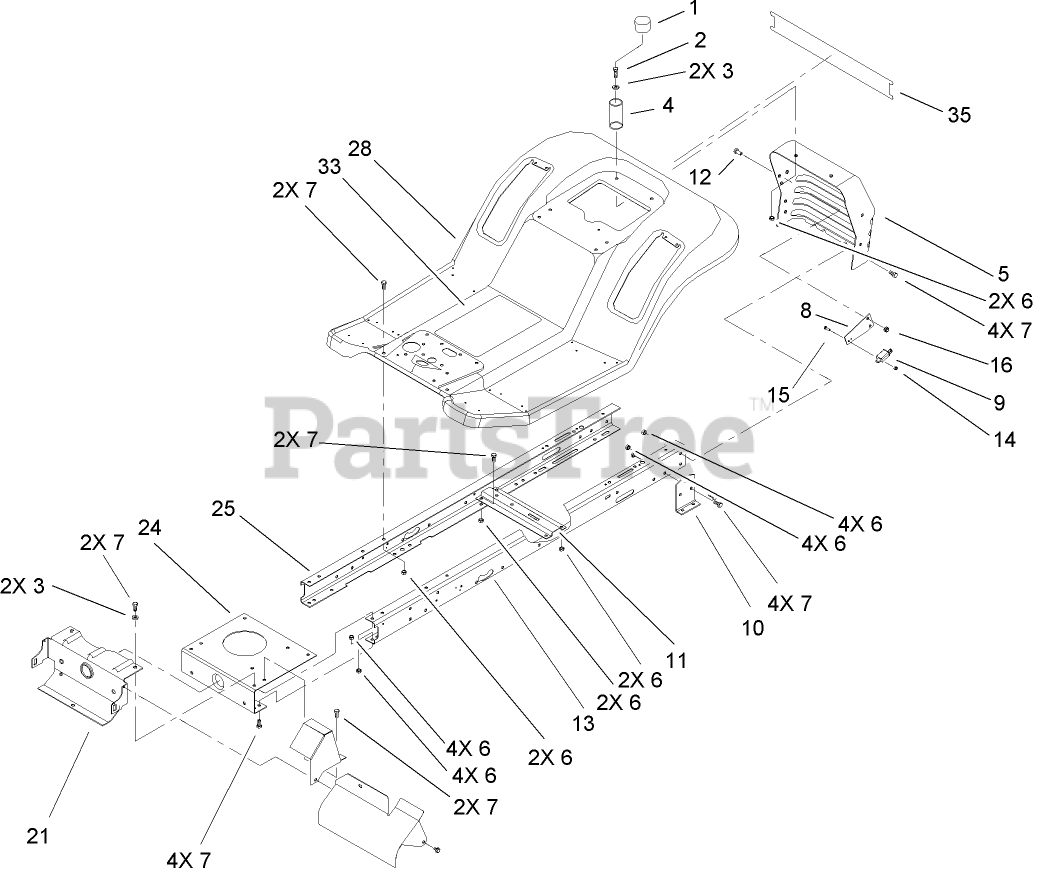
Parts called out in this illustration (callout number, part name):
1	CAP-PROTECTOR
2	SCREW-HH
3	WASHER-PLAIN
4	SPRING-COMPRESSION
5	SUPPORT-SEAT/REAR HITCH
6	NUT-LOCK, NI
7	SCREW-HH
8	PLATE-SWITCH
9	SWITCH-POLE, SINGLE
10	BRACKET-TRANSAXLE, MOUNTING
11	BRACKET-IDLER PIVOT
12	SCREW-HH
13	RAIL-FRAME, LH
14	NUT-LOCK
15	SCREW-SHH
16	NUT-LOCK, NI
24	PLATE-MOUNTING, ENGINE
25	RAIL-FRAME, RH
28	REAR BODY ASM
33	DECAL-INSTRUCTION
35	DECAL-REAR FENDER, LAWN TRACTORS
